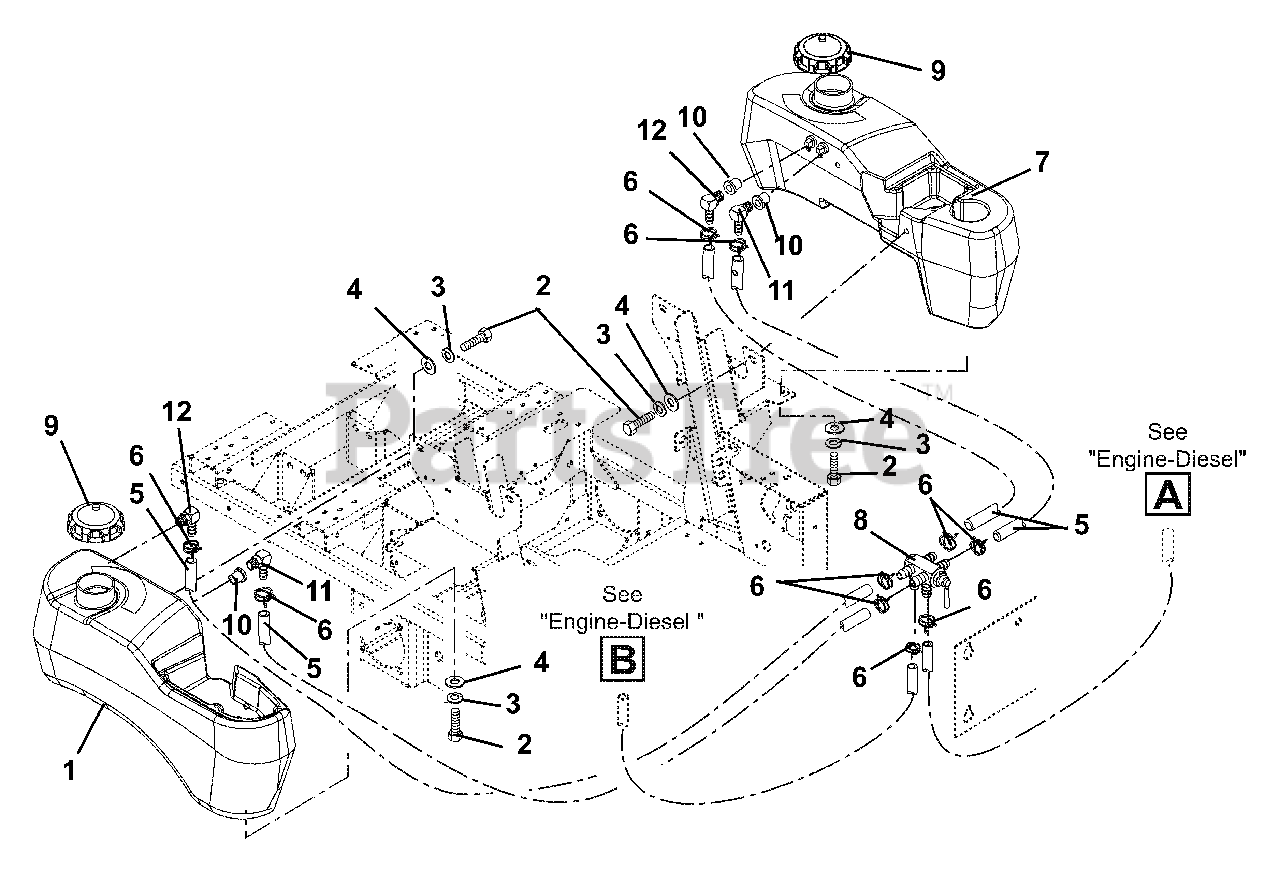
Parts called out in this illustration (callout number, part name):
1	TANK, FUEL-RH(W/RTN)W/O HOSE
2	@BLT-HEX .31-18X.75 GR5 YWZC
3	@WSHR-LK .31X.078 REG YWZC
4	@WSHR-FL-STL.38X.875X.083 YWZC
5	HOSE,5/16 ID
6	CLAMP, HOSE WIRE .520/.550
7	TANK, FUEL-LH(W/RTN)W/O HOSE
8	VALVE, FUEL
9	CAP, FUEL
10	BSHG-FLG .375 X 1.062 X .625 R
11	FITTING, TANK ELBOW .31 HOSE
12	FITTING, TANK (5/16 ELBOW)
